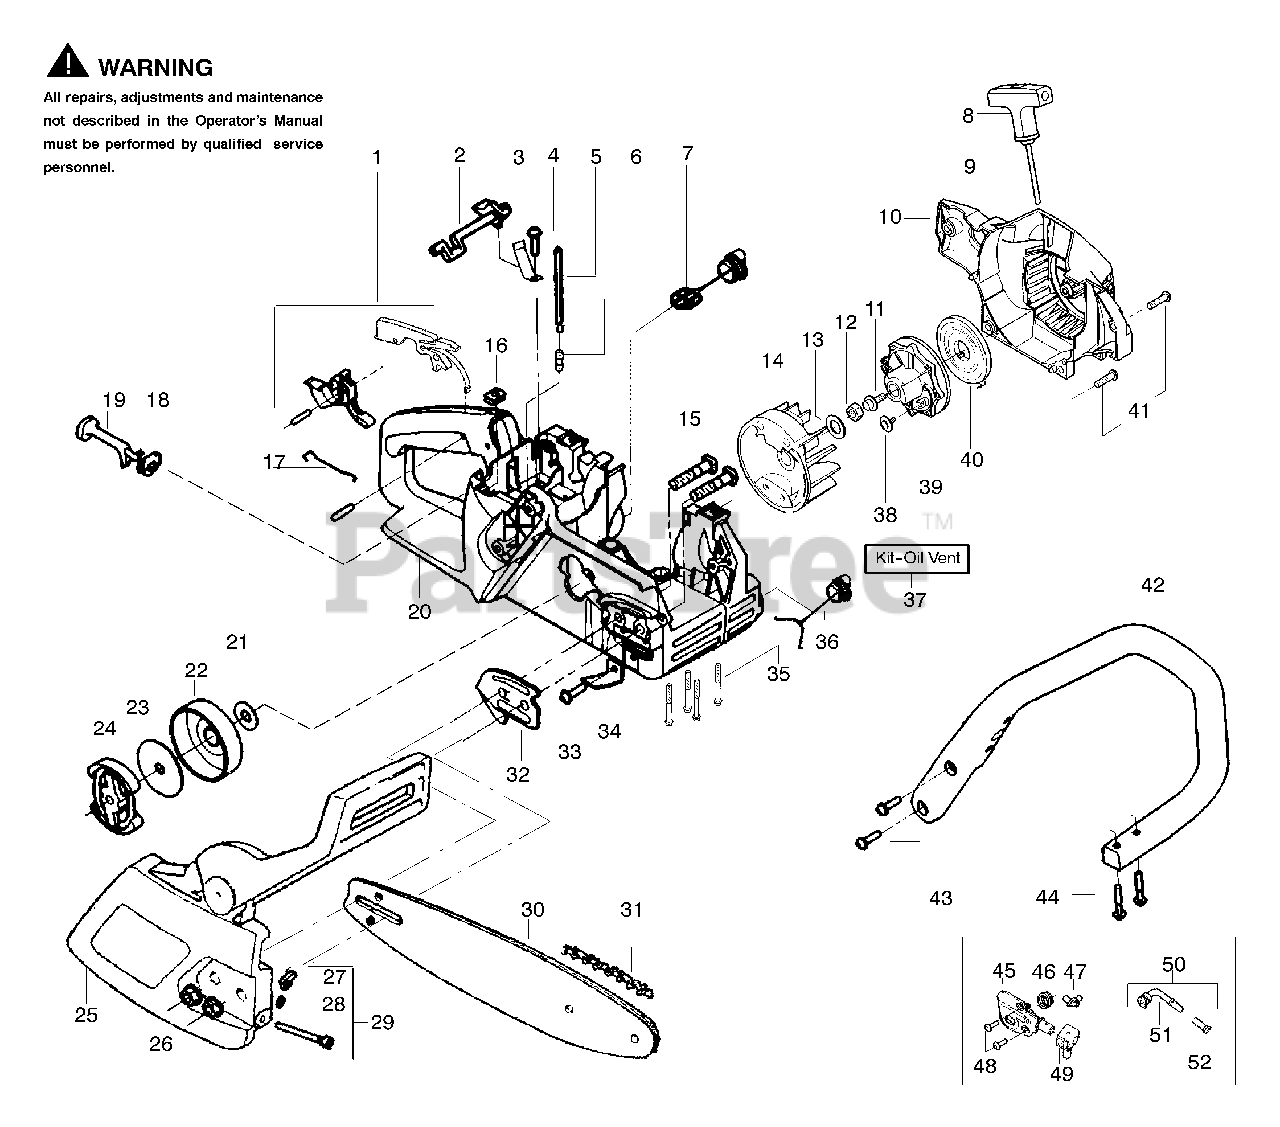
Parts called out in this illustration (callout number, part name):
1	Kit-Trigger & Lockout
2	Lever-Switch
3	Spring-Switch
5	Kit-Fuel Line (Large)
7	Assy-Fuel Cap
8	Handle-Starter
9	Kit-Rope
10	Housing-Fan
12	Nut-Flywheel
13	Washer-Flywheel
14	Assy-Flywheel
15	Bolt-Bar Mounting
16	Nut-Speed
17	Wire-Throttle
18	Grommet-Choke Knob
19	Lever-Choke
20	Assy-Chassis
21	Washer - Thrust
22	Assy-Drum W/brg.
23	Washer-Clutch
24	Assy. - Clutch
25	Assy-Chain Brake
26	Nut-Bar Mounting
27	Pin-Bar Adjust
28	Retainer-Bar Adjust
29	Kit-Bar Adjust
31	Chain-14"
32	Plate-Bar Mounting
34	Chain Catcher
36	Assy-Oil Cap
37	Kit-Oil Vent
39	Pulley-Starter
40	Spring-Starter
42	Handle-Front
45	Kit-Oil Pump
46	Gear-Worm Spring
47	Elbow-Oil Pickup
49	Seal Block
50	Assy-Oil-Pickup
51	Pickup-Oiler
52	Filter-Oil
